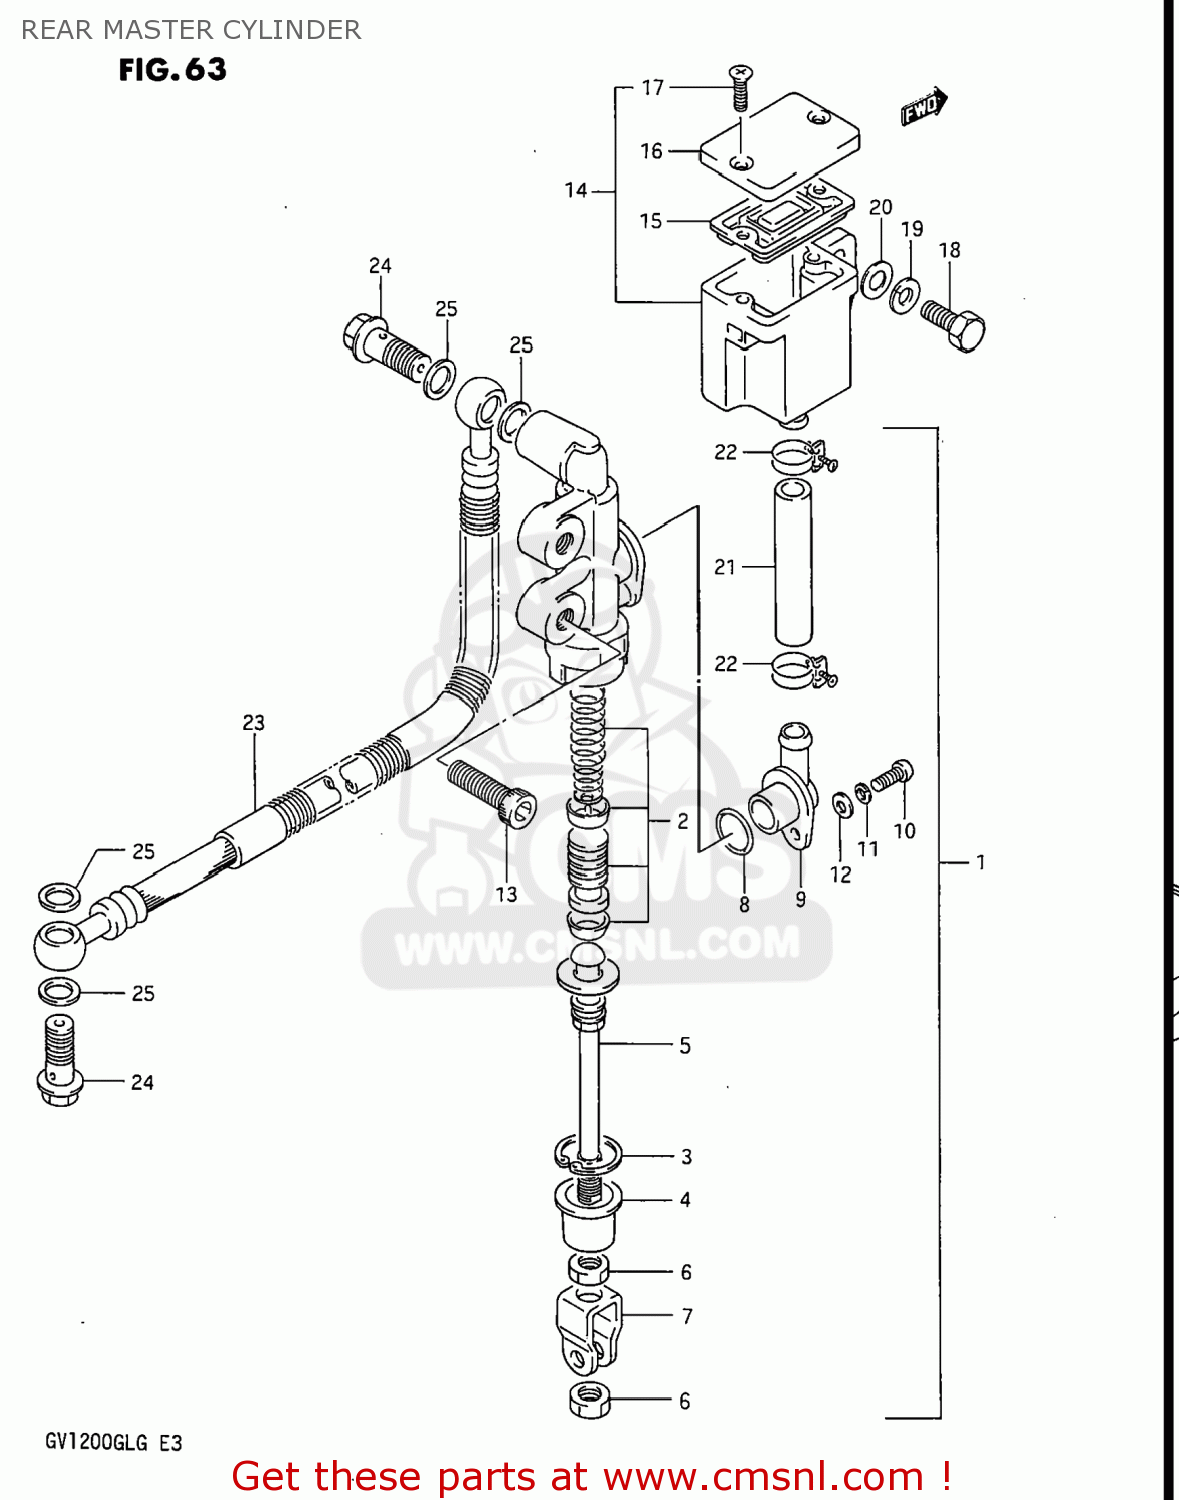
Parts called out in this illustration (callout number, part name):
2	PISTON/CUP SET
3	CIRCLIP
4	BOOT
5	ROD,PUSH
6	NUT
7	YOKE
8	O RING
9	CONNECTOR
10	SCREW
11	LOCK WASHER
12	WASHER
13	BOLT, REAR (8X30)
14	TANK ASSEMBLY,RESERVOIR
15	DIAPHRAGM
16	CAP
17	SCREW
18	BOLT 6X16
19	WASHER,LOCK
20	WASHER
21	HOSE,RESERVOIR TANK
22	CLAMP
23	HOSE,REAR BRAKE
24	BOLT UNION
25	WASHER(10X15X1.5)
